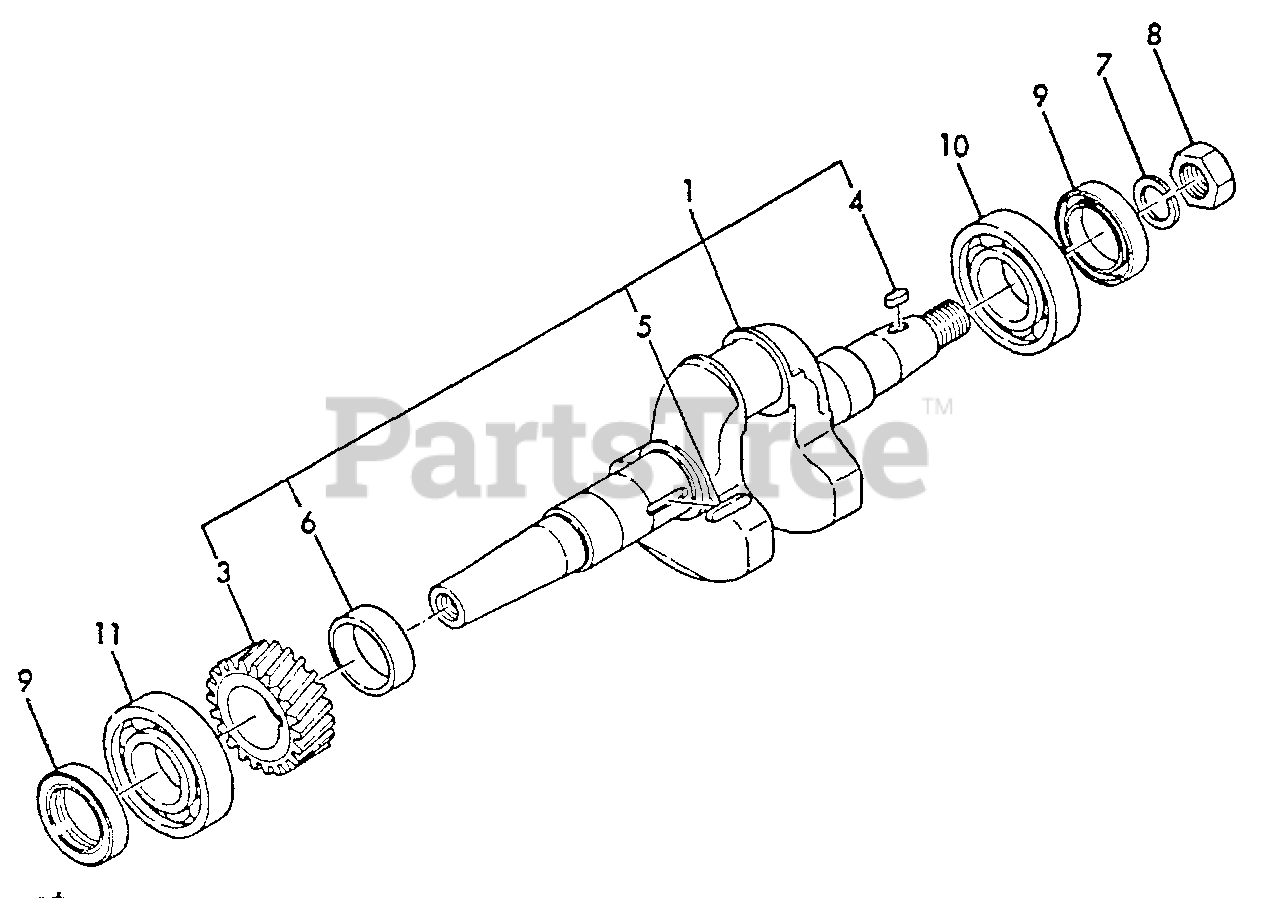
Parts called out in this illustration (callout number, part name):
1	CRANKSHAFT ASSY
3	GEAR, CRANKSHAFT
4	KEY - 4X10
5	KEY - 4X24
6	SPACER, GEAR
7	LOCKWASHER - 10
8	NUT - 16
9	SEAL, OIL
10	BEARING, BALL - 6205C3
11	BEARING, BALL - 6206C4
